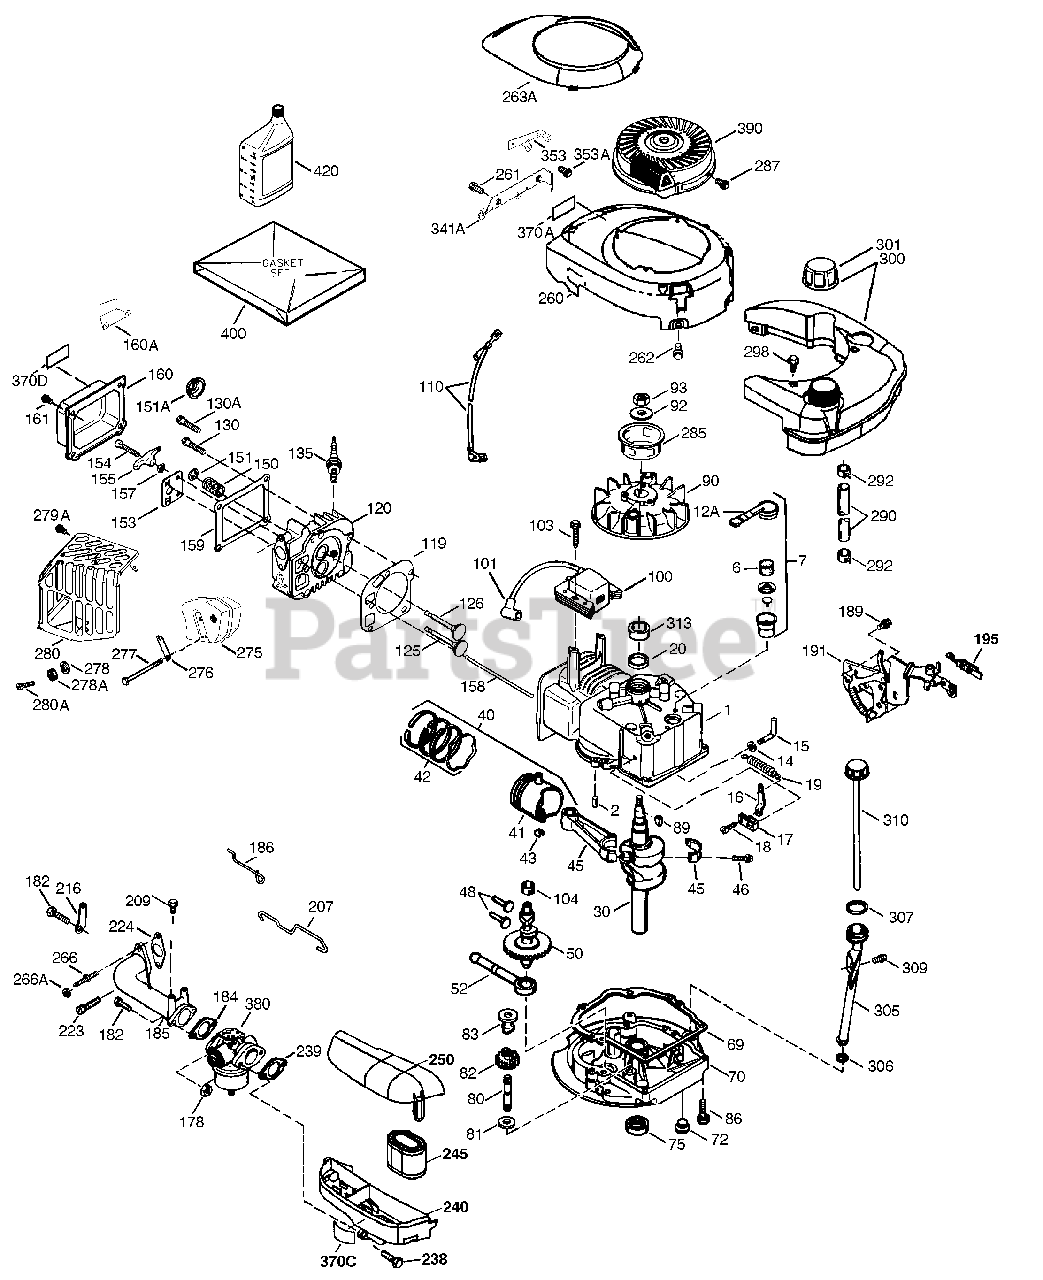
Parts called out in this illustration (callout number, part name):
1	Cylinder (Incl. 2 & 20)
2	Dowel Pin
6	Breather Element
7	Breather Body ASM(Incl. 6 & 12A)
12A	Breather Cover & Tube
14	Washer
15	Governor Rod(Incl. 14)
16	Governor Lever
17	Governor Lever Clamp
18	Screw, Torx T-15
19	Extension Spring
20	Oil Seal
30	Crankshaft
40	Piston, Pin & Ring Set(Std.)
40	Piston, Pin & Ring Set(.010" OS)
40	Piston, Pin & Ring Set(.020" OS)
41	Piston & Pin ASM(Std.)
41	Piston & Pin ASM(.010" OS)(Incl. 43)
41	Piston & Pin ASM(.020" OS)(Incl. 43)
42	Ring Set (Std.)
42	Ring Set (.010" OS)
42	Ring Set (.020" OS)
43	Piston Pin RetainingRing
45	Connecting Rod ASM(Incl. 46)
46	Connecting Rod Bolt
48	Valve Lifter
50	Camshaft
52	Oil Pump ASM
69	Mounting FlangeGasket
70	Mounting Flange(Incl. 72 thru 83)
72	Oil Drain Plug
75	Oil Seal
80	Governor Shaft
81	Washer
82	Governor Gear ASM(Incl. 81)
83	Governor Spool
86	Screw
89	Flywheel Key
90	Flywheel
92	Belleville Washer
93	Flywheel Nut
100	Solid State Ignition
101	Spark Plug Cover
103	Screw, Torx T-15
104	Cam Bushing
110	Ground Wire
119	Cylinder Head Gasket
120	Cylinder Head
125	Exhaust Valve (Std.)(Incl. 151)
125	Exhaust Valve (1/32
126	Intake Valve (Std.)(Incl. 151)
130	Screw
130A	Screw
135	Resistor Spark Plug(RN4C)
150	Valve Spring
151	Valve Spring Cap
151A	Intake Valve Seal
153	Push Rod Guide
154	Rocker Arm Stud
155	Rocker Arm
157	Lock Nut
158	Push Rod
159	Rocker Arm Cover
160	Rocker Arm Cover
160A	Heat Shield
161	Screw, Torx T-30
178	Nut & Lock Washer
182	Screw
184	Carburetor To IntakePipe Gasket
185	Intake Pipe (Incl.223 & 224)
186	Governor Spring
189	Screw
191	S.E. Brake Bracket
195	Terminal
207	Throttle Link
209	Screw
216	Speed Adjuster Lever
223	Screw
224	Intake Pipe Gasket
238	Screw
239	Air Cleaner Gasket
240	Air Cleaner Body
245	Air Cleaner Filter
250	Air Cleaner Cover
260	Blower Housing
261	Screw, Torx T-30
262	Screw
263A	Starter Grill
266	Screw
266A	Lockwasher
276	Locking Plate
277	Screw
278	Spacer
278A	Bushing Control Lever
279A	Screw, Torx
280	Heat Shield-Muffler
280A	Screw
285	Starter Cup
287	Screw
290	Fuel Line
292	Fuel Line Clamp
298	Screw
300	Fuel Tank (Incl. 292 & 301)
301	Fuel Cap
305	Oil Fill Tube
306	"O"-Ring
307	"O"-Ring
309	Screw
310	Dipstick
313	Spacer
341A	Offset Bracket
353	Bracket Spacer
353A	Screw
370A	Lubrication Decal
370C	Primer Decal (3X)
370D	Caution Decal
380	Carburetor (Incl. 184)
390	Rewind Starter
400	Gasket Set
420	SAE30 4-Cycle Engine Oil (Quart)
